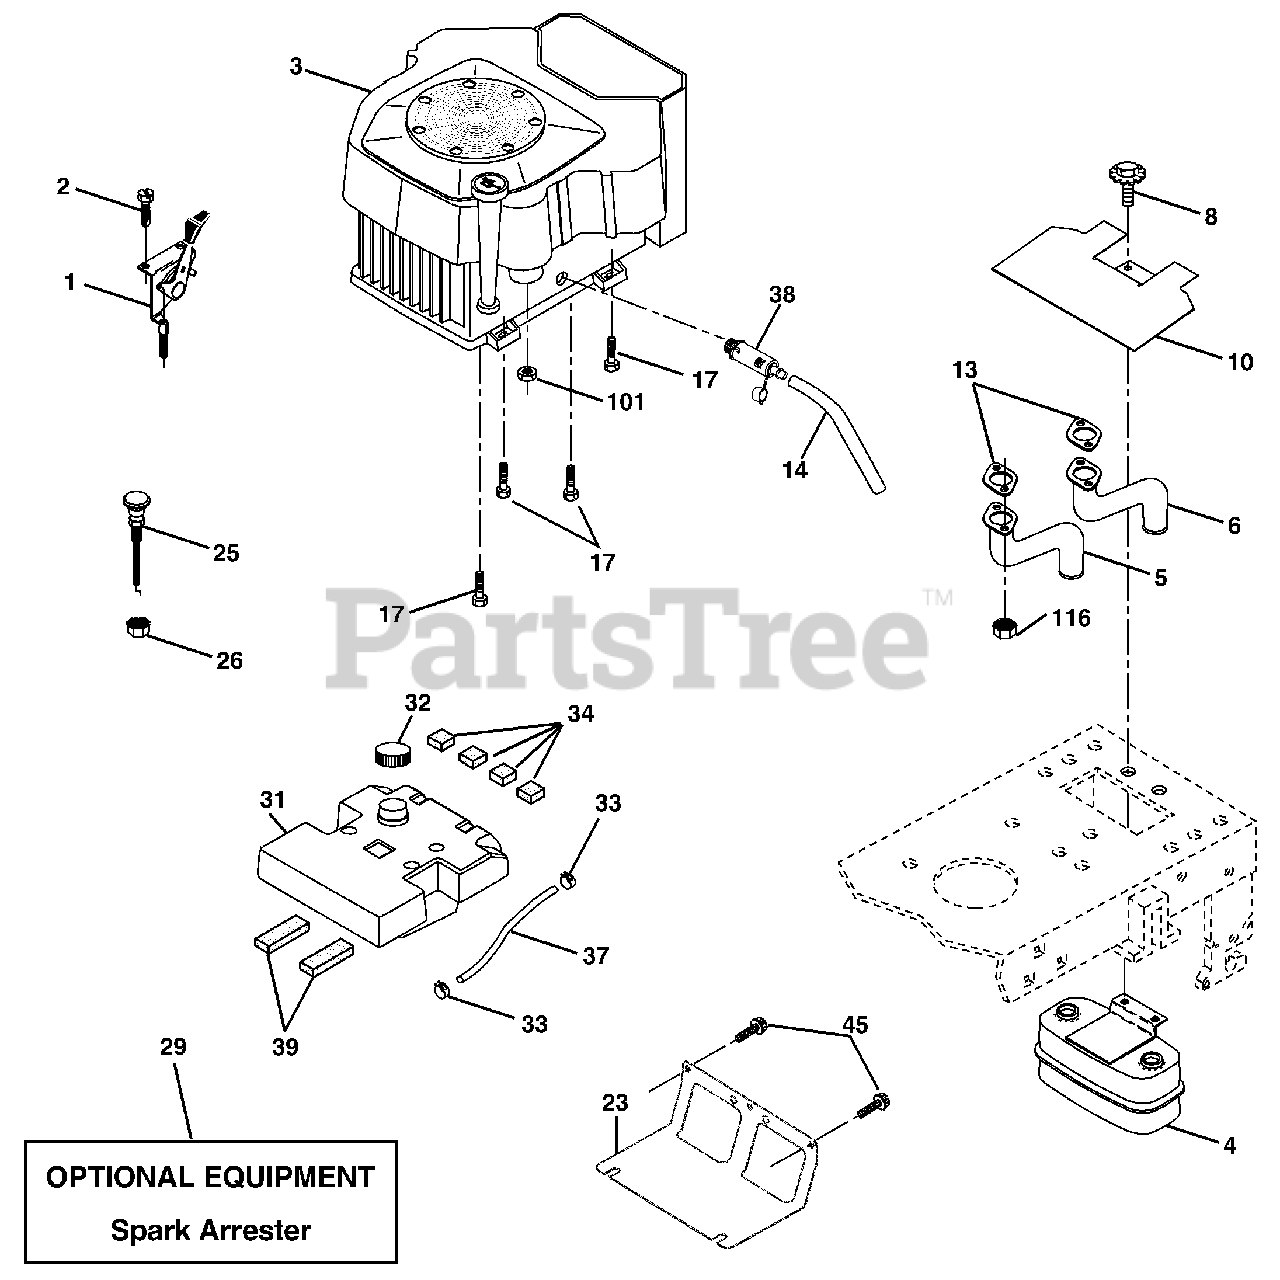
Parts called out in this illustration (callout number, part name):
1	Control Th/ch CB EEC. 428
2	Screw HWHD Hi-Lo #13-16 x 3/4
5	Pipe Exhaust LH
6	Pipe Exhaust RH
8	Bolt 5/16-18 Unc x 3/4 w/Sems
10	Shield Heat Muffler
14	Tube Drain Oil Easy
16	Washer Lock Ext Tooth 3/8
17	Screw 3/8-16 x 1-1/2
23	Shield Browning/Debris Guard
25	Control Choke
26	Nut Keps 3/8-24 Unf
29	Kit Spark Arrestor
32	Cap Asm Fuel Top Vented N/Lang
33	Clamp Hose Black
34	Pad Spacer 1 x 1 x 1
37	Line Fuel
38	Plug Drain Oil Easy
39	Pad Idler 1.75 x .75 x .06
45	Screw 3/8-16 x .75 SMGML
101	Nut Flange M8-1.25
116	Nut Hex Flange Toplock M8-1.25
